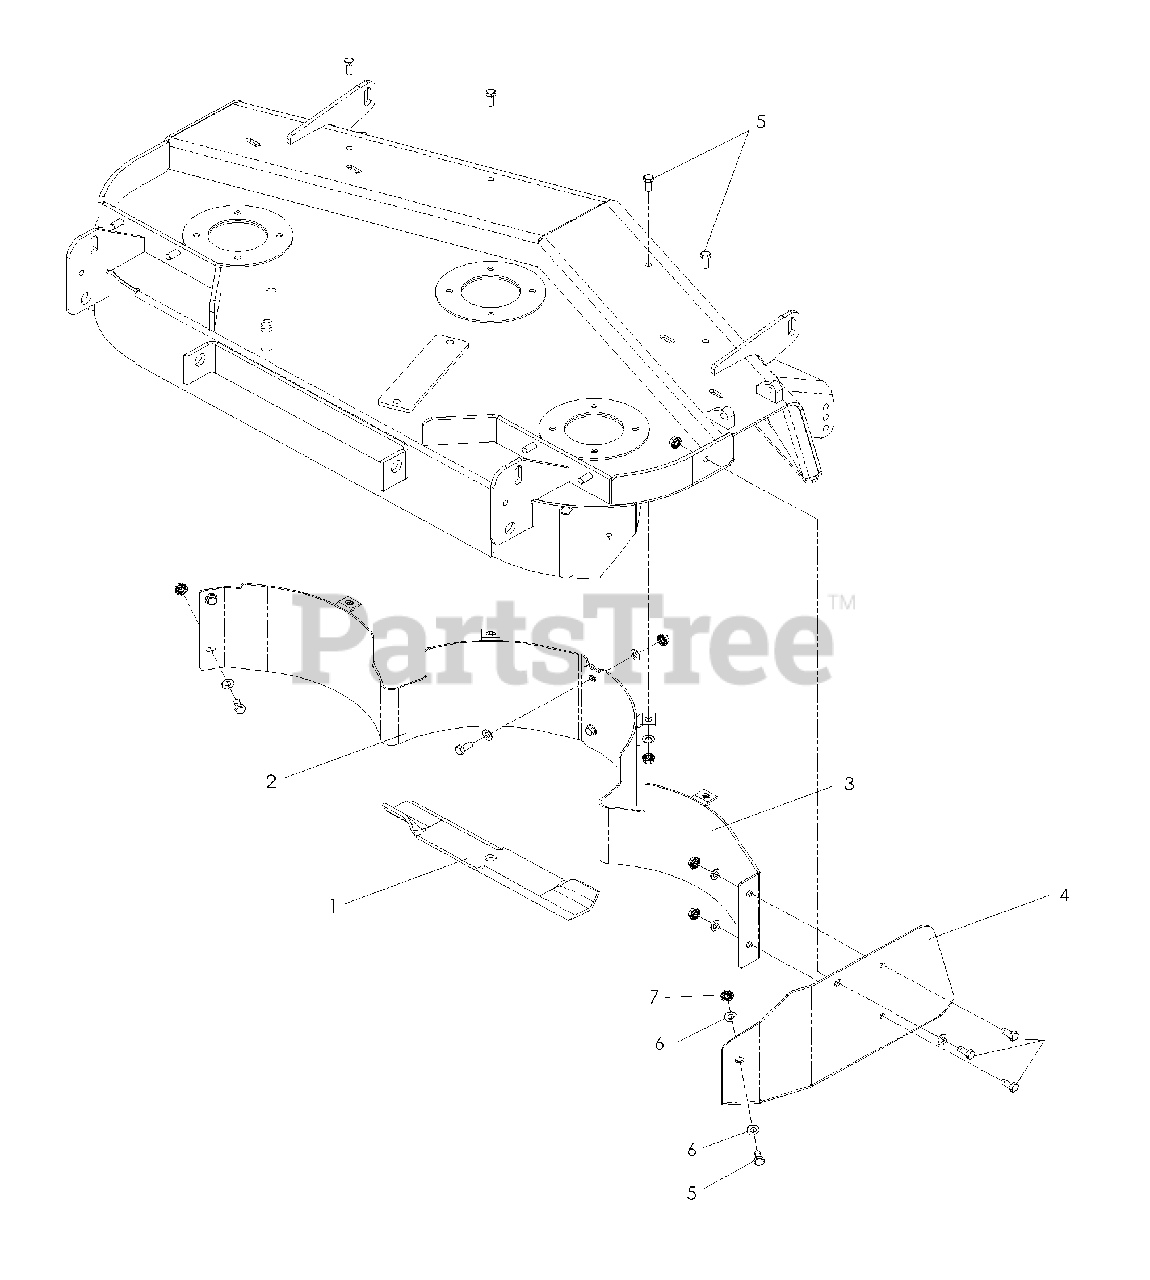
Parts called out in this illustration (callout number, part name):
1	42" MULCH BLADE, 14 7/8"
1	48" MULCH BLADE, 16 1/4"
1	52" MULCH BLADE, 18"
1	61" MULCH BLADE, 21"
2	MULCH BAFFLE, LEFT, 42"
2	MULCH BAFFLE, LEFT, 48"
2	MULCH BAFFLE, LEFT, 52"
2	MULCH BAFFLE, LEFT, 61"
3	MULCH BAFFLE, RIGHT, 42"
3	MULCH BAFFLE, RIGHT, 48"
3	MULCH BAFFLE, RIGHT, 52"
3	MULCH BAFFLE, RIGHT, 61"
4	MULCH CAP, 42"
4	MULCH CAP, 48"
4	MULCH CAP, 52"
4	MULCH CAP, 61"
5	HCS 5/16 -18 x 3/4
6	WASHER 5/16 SAE
7	NUT 5/16 -18 WHIZLK
